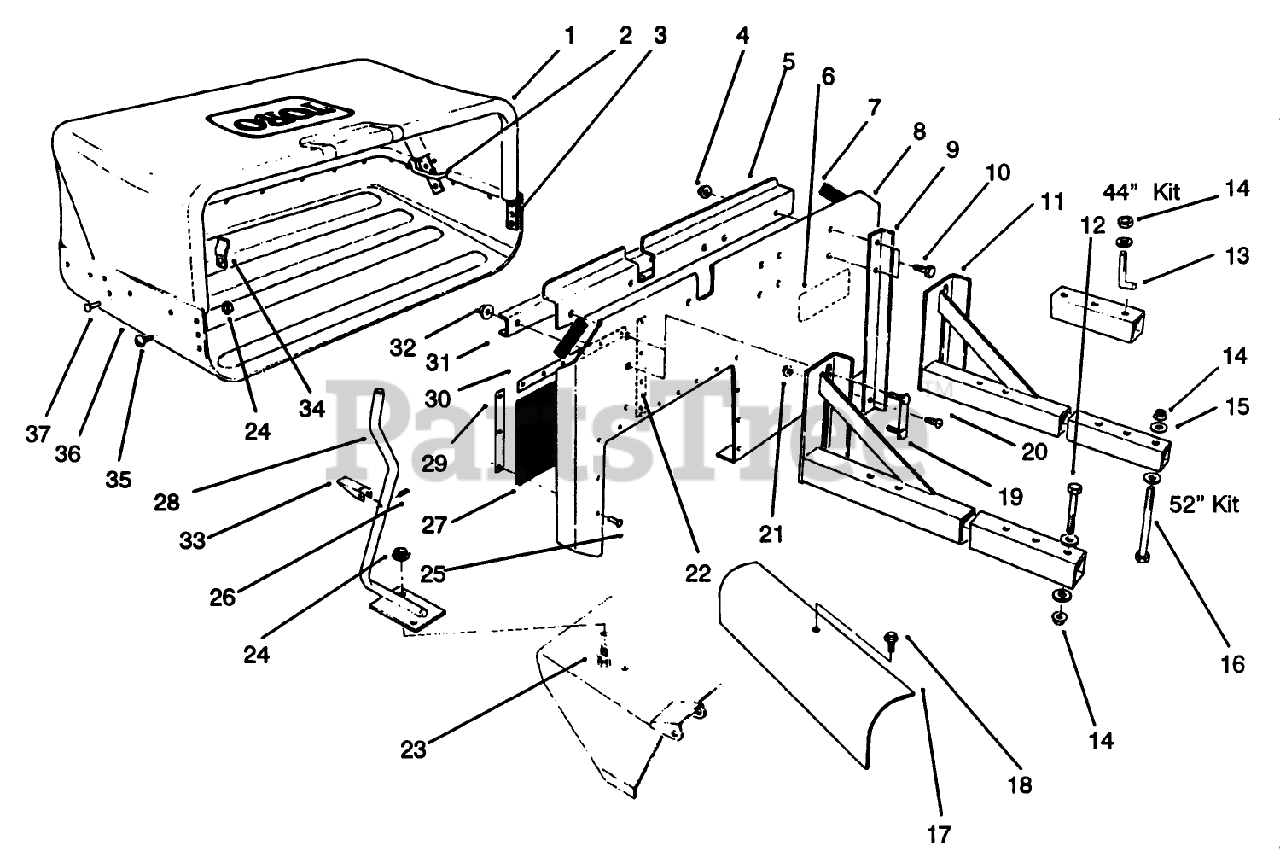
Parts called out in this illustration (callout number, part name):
1	Bag-Cloth
2	Rod-Cloth
3	Tube-Bag Support
4	NUT-HHF, WHIZ
5	Support-Bag
6	DECAL-DANGER
7	PAD-RUBBER
8	Panel-Back
9	Support-Panel
10	SCREW-HH
11	Beam-Mounting
12	SCREW-HH
13	Bolt-Special
14	NUT-LOCK, NI
15	WASHER-FLAT
16	SCREW-HH
17	Baffle-44in
18	Screw-HH
19	Retainer-Bolt
21	NUT-HF
22	STRIP-Seal, 10in
23	SCREW-HH
24	NUT-HF
25	RIVET-POP
26	PIN-SPRING
28	Rod-Lockup
29	STRIP
30	STRIP-SEAL, 16in
31	Support-Channel
32	NUT-LOCK, FLANGE
33	LATCH-LOCKUP
34	CLIP-HALF
35	SCREW-PPH
36	TRAY-BAG, GRASS
37	RIVET-BLIND
